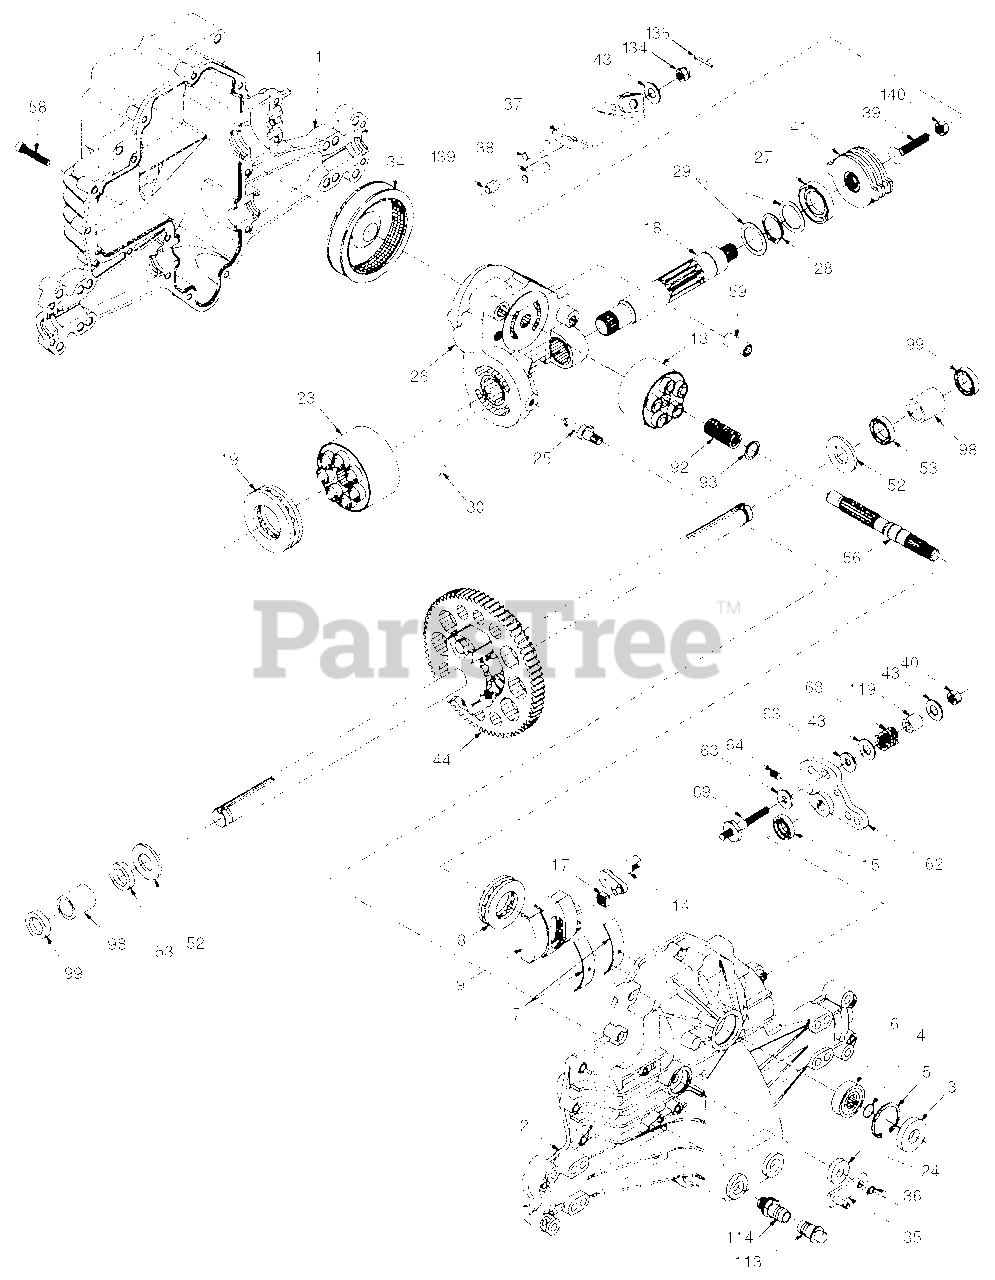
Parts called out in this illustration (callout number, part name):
1	Housing, Lower
2	Assembly, Upper Housing
4	Ring, Wire Retaining
5	Ring, Retaining
6	Bearing, Shaft Ball
7	Bearing, Cradle
8	Bearing, Thrust 30 x 52 x 13
9	Swashplate, Variable
13	Block, Cylinder Assembly
14	Arm, Trunnion
17	Guide, Slot
18	Shaft, Motor
19	Bearing, Thrust 42 x 68 x 16
23	Block, Cylinder Assembly
24	Seal, Lip 10 x 25 x 7
25	Actuator, Bypass
26	Center Section Assembly Kit
27	Seal, Lip 26 x 42 x 8
28	Ring, Retaining
29	Washer 26 x 35 x 1
34	Oil Filter Element
35	Arm, Bypass
36	Ring, Retaining
37	Arm, Actuating
38	Pin, Actuating
39	Bolt 5/16-24 x 1-3/4
40	Locknut, Hex 5/16-24 UNJC
41	Brake Rotor/Stator Kit
43	Washer 7/16 x 7/8 x .060
44	Differential Assembly
52	Washer 3/4 x 1.5 x .13
53	Seal .75 x 1.25 x .250
54	O-Ring .103 x 2.987 ID
56	Shaft, Input
58	Bolt 1/4-20 x 1.38
59	Pin .5 OD x .43 ID x .750
62	Arm, Control
63	Puck, Dampener
65	Bolt #8-32 x .875
69	Stud 5/16-24
92	Spring, Block
93	Washer, Block Thrust
98	Sleeve Bearing
99	Seal, Wiper
113	Cap, Vent Assembly
114	Fitting, O-Ring Assembly
119	Spacer
134	Nut, Castle 5/16-24
135	Pin, Cotter
